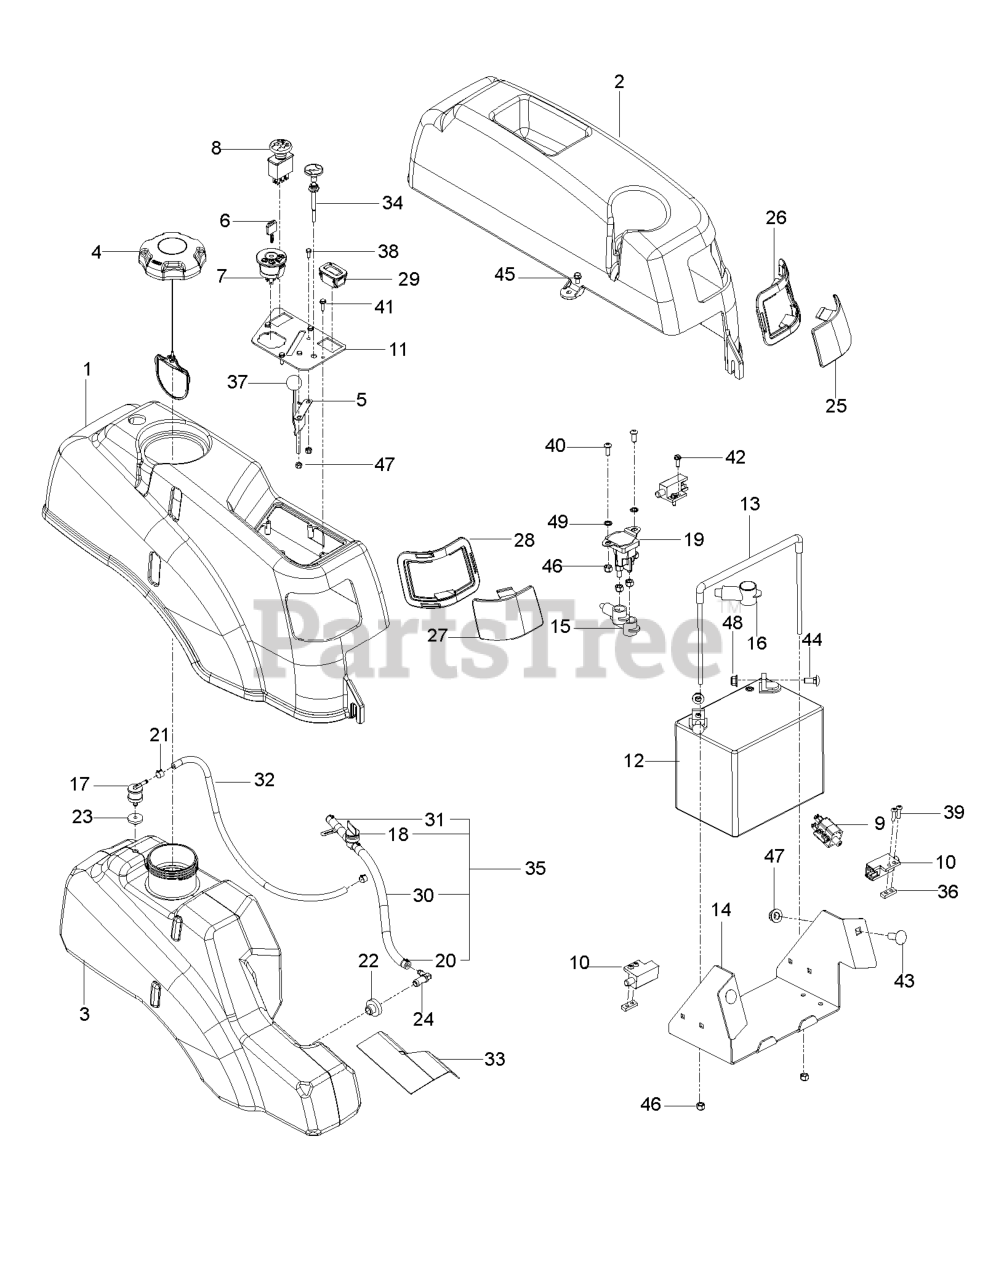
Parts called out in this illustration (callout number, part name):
1	FENDER RT, GRAY
2	FENDER, LT
3	TANK.FUEL.RT.EPA
4	CAP, FUEL
5	THROTTLE CONTROL W/BALL KNOB
6	KEY
7	RP IGNITION SWITCH
8	RP SWITCH.PTO.8.TERMINAL.RED
9	SWITCH, BRAKE 3P
10	SWITCH INTERLOCKT
11	CONSOLE.PLATE.BLACK
12	BATTERY, 12 V 330 AMP
13	BATTERY TIE DOWN ASSEMBLY
14	BOX, BATTERY, BLACK
15	TERMINAL COVER-SM
17	VALVE.FUEL.CHECK
18	FUEL VALVE
20	HOSE CLAMP
21	CLAMP, HOSE
22	RUBBER GROMMET
23	GROMMET, CHECK VALVE
24	STEM, FUEL TANK
25	LENS, COLORED LEFT
26	LEFT HEADLIGHT RIM GREY
27	LENS, COLORED RIGHT
28	RT HEADLIGHT RIM GREY
29	HOUR METER
30	GAS LINE 10"
31	FUEL LINE 3"
32	HOSE, VAPOR 3/16 X 15"
33	SHIELD, HEAT
34	CHOKE CONTROL, COMPLETE
35	FUEL LINE ASSY
36	TAPPED PLATE
37	KNOB.ROUND.BALL.BLACK
38	HCS #10-24 X 1/2
39	SCR #10-24 X .75 SKT HD BLK
40	SCR 1/4-20 X 5/8 BTN SKT HD ZD
41	SCR #10-12X3/4 HEX WAS HD ZD
42	SCREW #10 X 1/2 SELF TAPPING
43	RHSNB 3/8C X 1
44	BOLT 5/16C X 3/4" CARRIAGE
45	BOLT 1/4-20 X 1/2 HWST
46	NUT.1/4-20.HEX.NYLOC.ZD
47	NUT 10-24 NYLOC
48	5/16-18 NYLOC FLANGE NUT
49	WASHER 1/4 INT TOOTH
